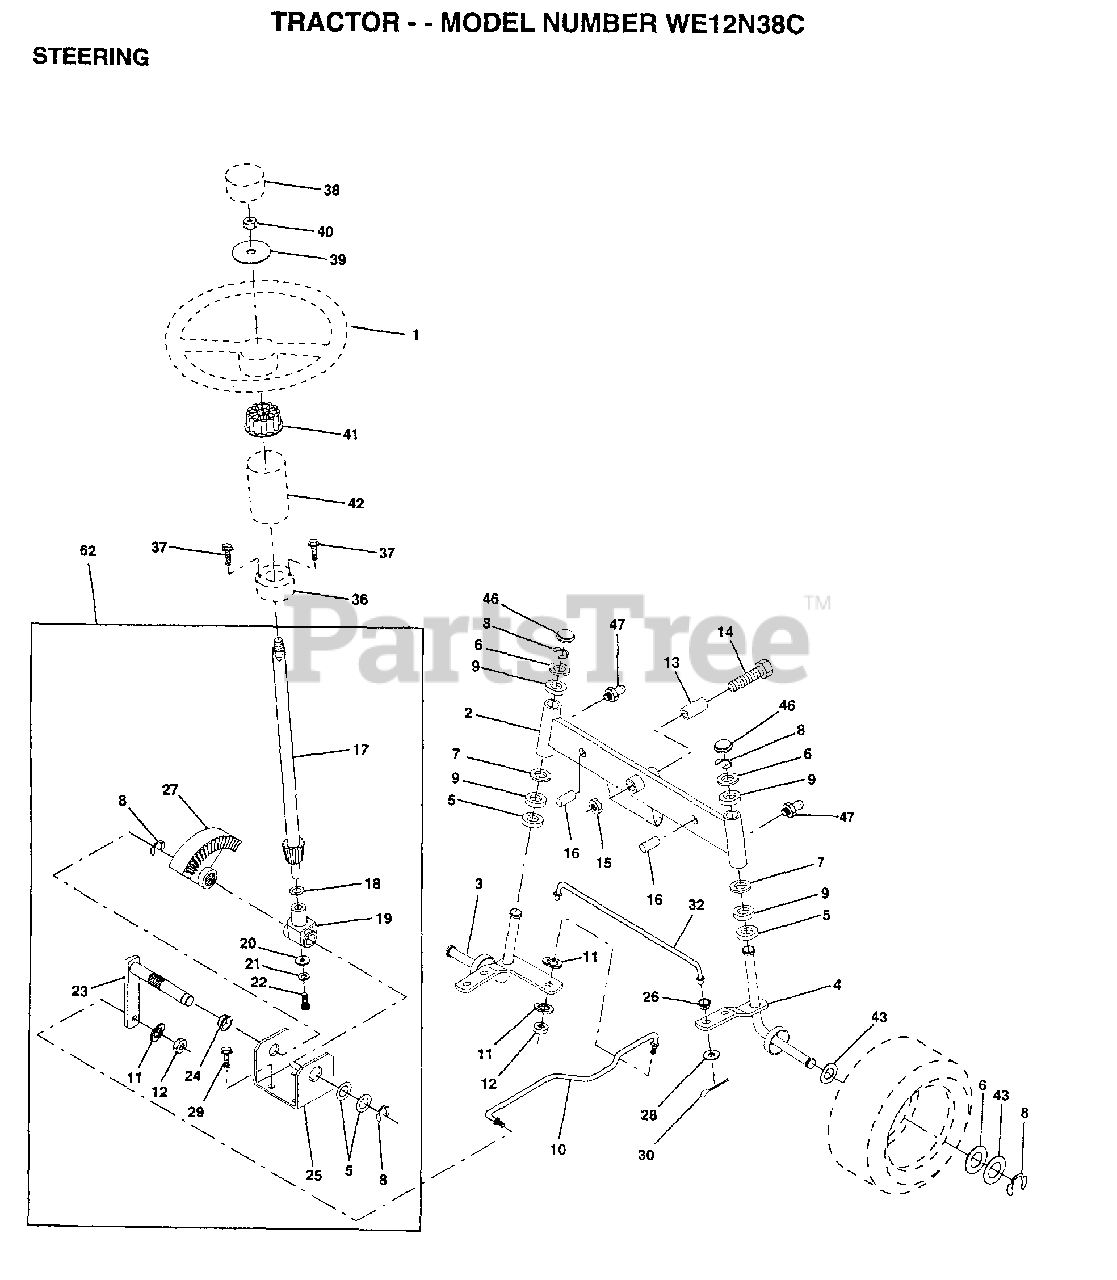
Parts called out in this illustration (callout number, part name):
2	AXLE ASM FRONT
3	SPINDLE LH
4	SPINDLE RH
5	WASHER .T
6	WASHER
7	WASHER
8	RING
9	COL. SRTG. BEAR.
11	LOCKWASHER
13	BEARING
14	BOLT HEX 5/8-11
15	"NUT-LOC,FLANGE LT"
16	AXLE PIN
17	SHAFT ASM
18	THRUST WASHER
19	SUPPORT.SHAFT
21	LOCKWASHER
22	SCREW.SCKTHD.CAP
24	NYLINER T
25	"BRKT,STEERING"
26	BUSHING.DRAGLINK
27	GEAR SECTOR
28	WASHER
29	SCREW
30	COTTER PIN
32	TIE ROD
37	"SCREW-TT,10-32 FL"
38	ST WHL INSERT CAP
39	WASHER T
40	GRIPCO NUT
41	ADAPTER-WHEEL LT
42	"TUBE, STR SHAFT"
43	WASHER
46	CAP
47	ZERK M
